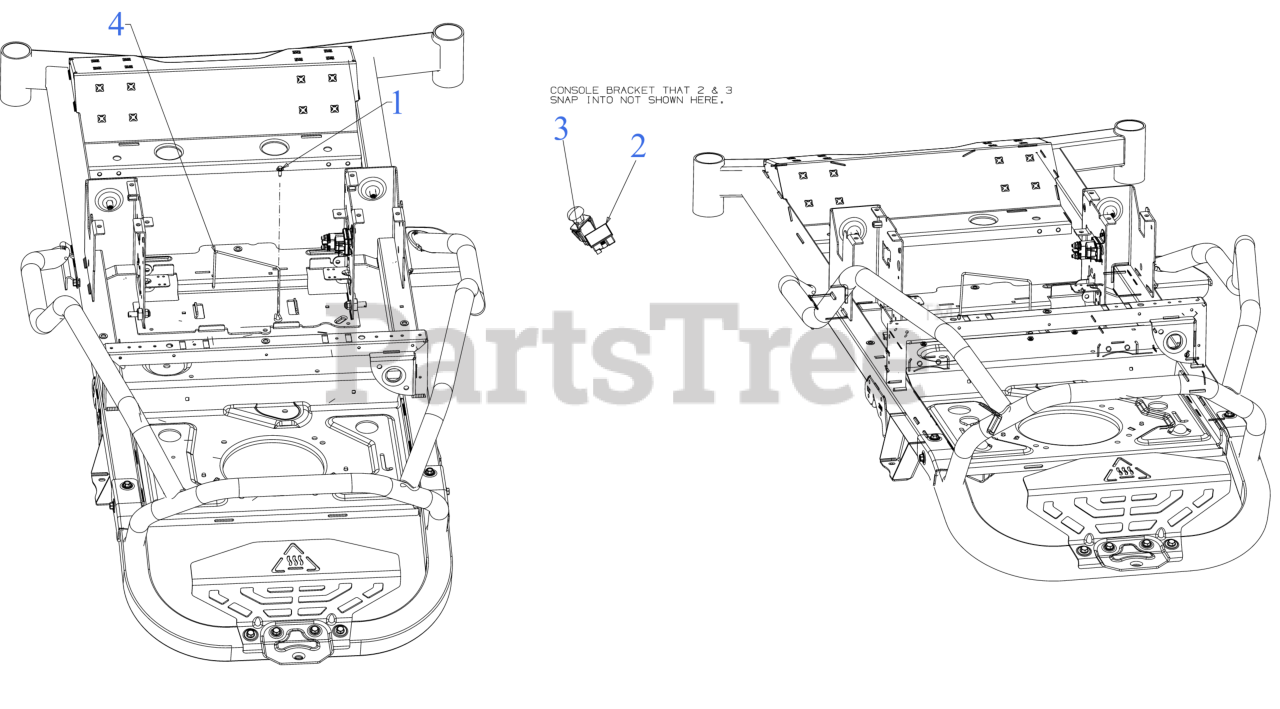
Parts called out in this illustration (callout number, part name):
1	SCREW M6-1 x .625
2	HOUR METER/SERVICE MINDER
3	PTO SWITCH (YELLOW KNOB)
4	BATTERY HOLD DOWN ROD
